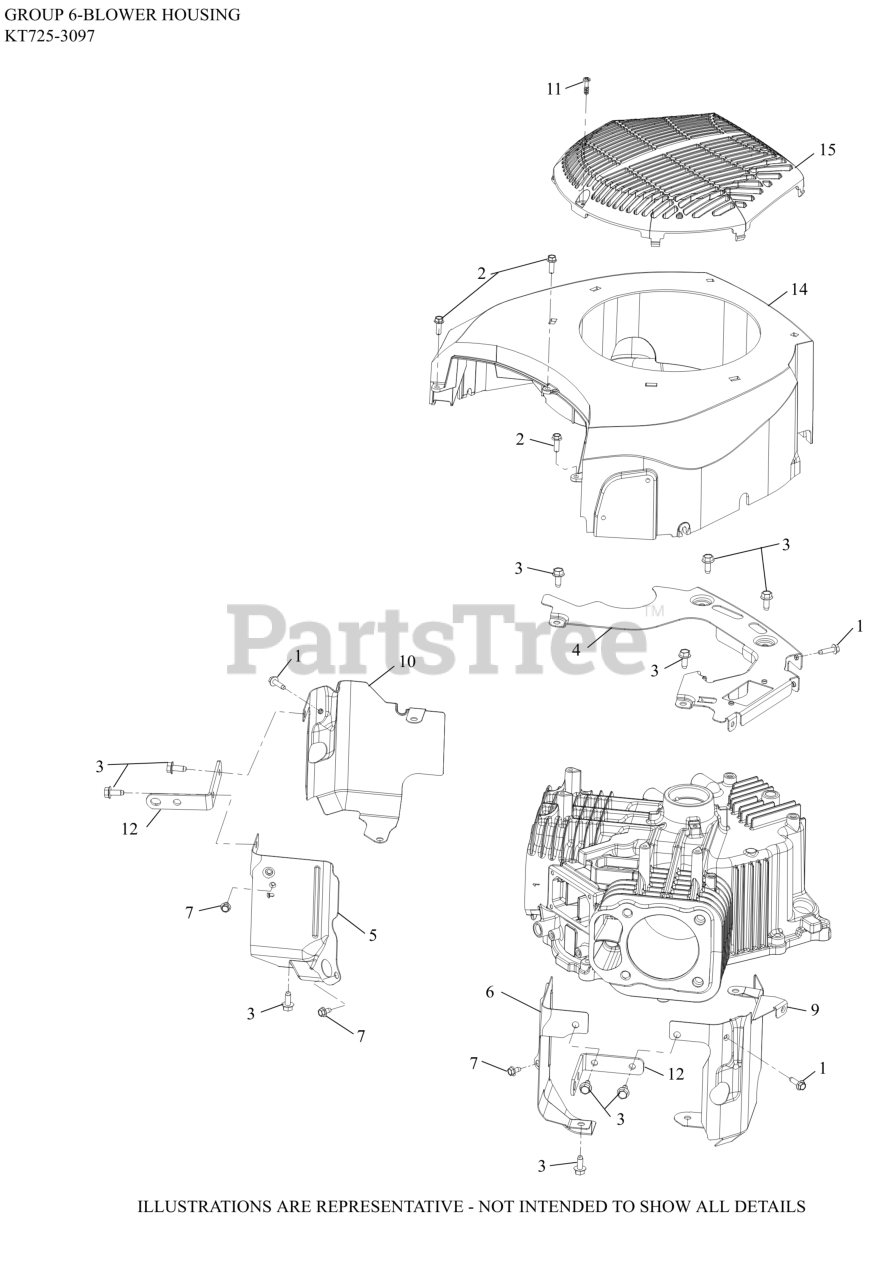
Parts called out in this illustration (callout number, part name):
1	SCREW, THD FRM-USE 25 086 473-S
2	SCREW, HI-LOW
3	SCREW, THREAD FORMING
4	PLATE, BACKING
5	BAFFLE, VALLEY #1
6	BAFFLE, VALLEY #2
7	SCREW, THREAD FORMING
9	BAFFLE, LEFT BARREL
10	BAFFLE, RIGHT BARREL
11	SCREW, M5-2.42 (PT) THREAD
12	STRAP, LIFTING
14	KIT, BLOWER HOUSING
15	GUARD, FIXED
